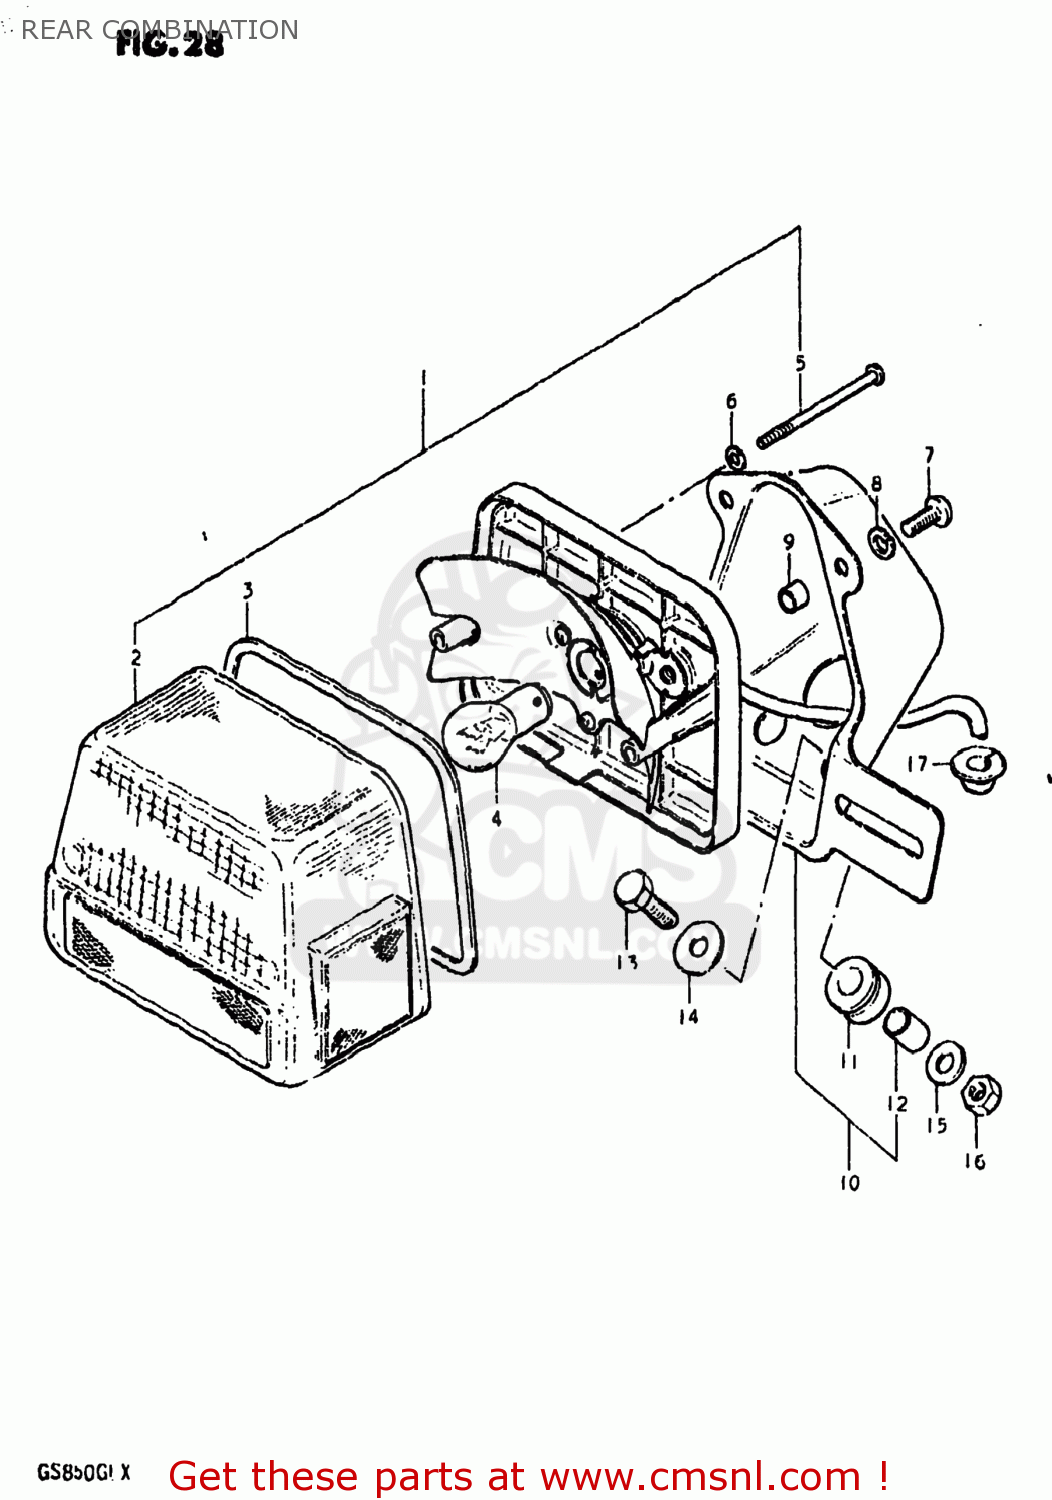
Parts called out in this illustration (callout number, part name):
1	LAMP UNIT,RR COMBNATION
2	LENS
3	GASKET (NAS)
4	BULB(12V23W)
5	SCREW
6	GASKET (NAS)
7	SCREW
8	LOCK WASHER
9	SPACER
10	BRACKET UNIT,TAIL LAMP
11	CUSHION
12	SPACER
13	BOLT
14	WASHER (6.5X20X1.2)
15	WASHER
16	NUT
17	GROMMET
